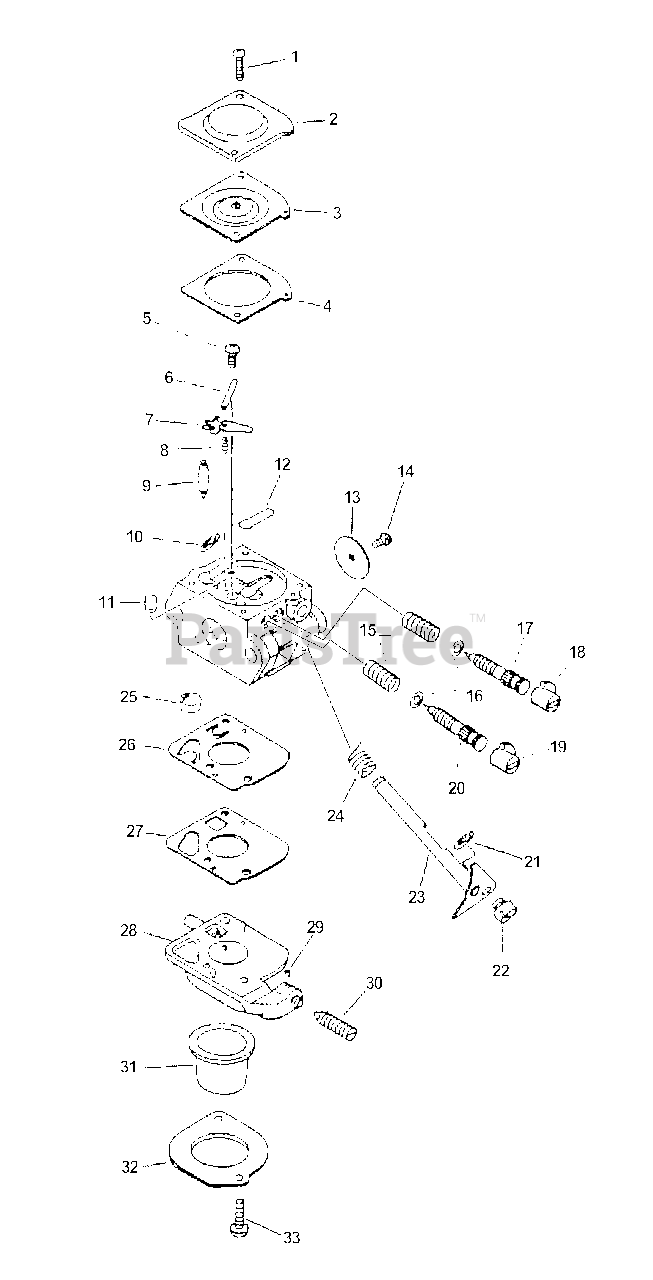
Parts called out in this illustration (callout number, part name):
2	COVER, METERING
3	DIAPHRAGM
4	GASKET, METERING
5	SCREW, METERING LEVER PIN
6	PIN, METERING LEVER
7	LEVER, METERING
8	SPRING, METERING LEVER
9	VALVE, INLET NEEDLE
10	RING, RETAINING
11	NOZZLE, CHECK VALVE
12	PLUG, WELCH
13	VALVE, THROTTLE
17	NEEDLE - LOW SPEED
18	CAP, LIMITER
19	CAP, LIMITER
20	NEEDLE - HIGH SPEED
21	RING, RETAINING
23	SHAFT, THROTTLE
24	SPRING, RETURN
25	STRAINER
26	DIAPHRAGM, PURGE
27	GASKET, PURGE
28	BASE, PURGE
29	PIECE, FRICTION
30	SCREW, IDLE ADJUST
31	BULB, PURGE
32	RETAINER, PURGE BULB
32	SCREW, RETAINER
